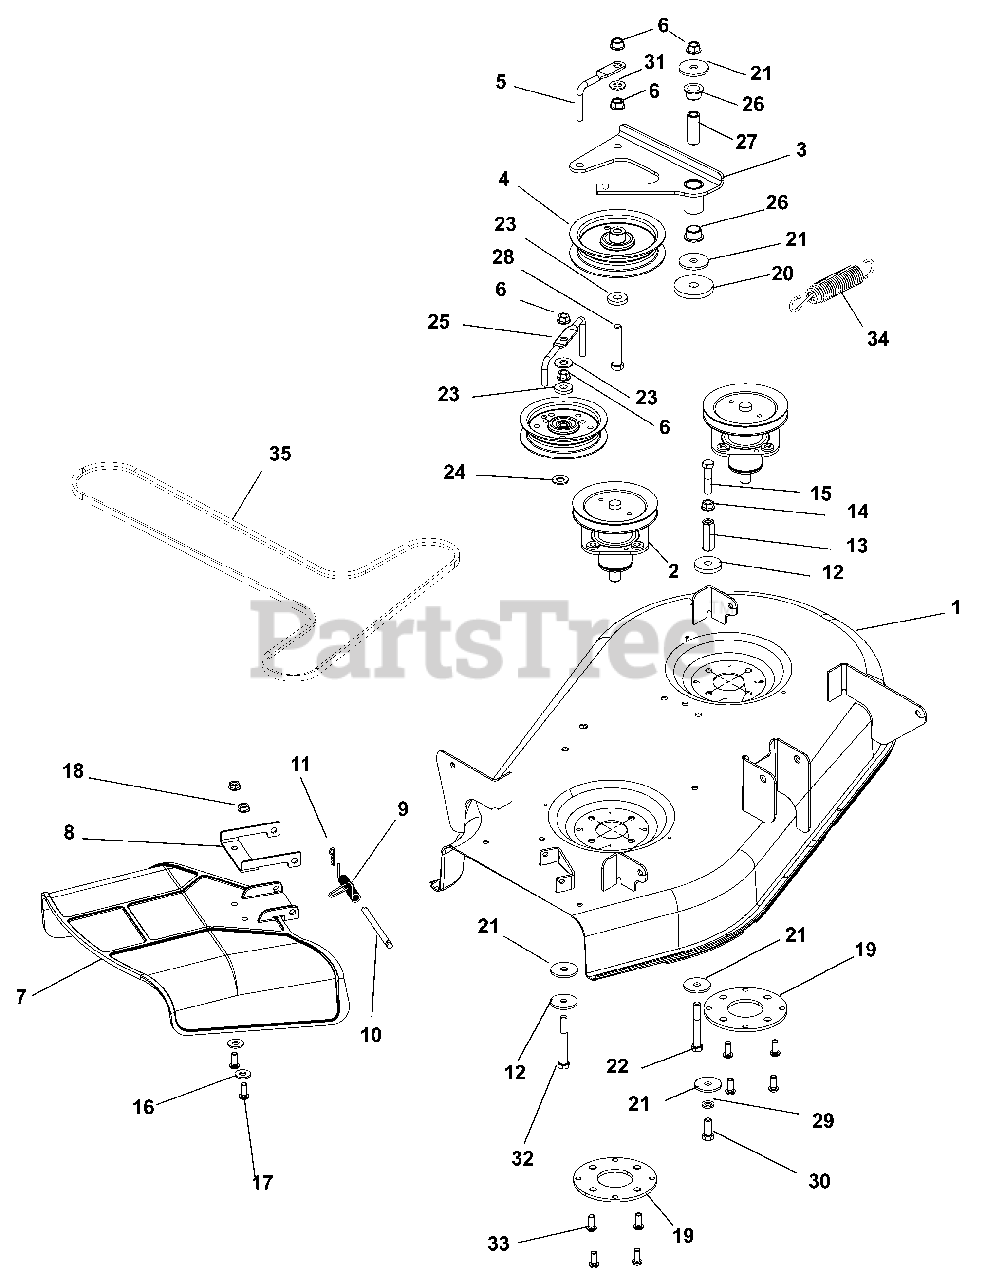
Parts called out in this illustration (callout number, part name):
1	Weldment, 34" Deck
2	Assembly, Spindle
3	Weldment, Idler Arm
4	Assembly, Idler 4"
5	Wireform, Belt Finger
6	Nut, Locking Top Flange .38-16
7	Chute, Side Discharge
8	Chute Reinforcement
9	Spring, Torsion
10	Pin, 5/16 x 3.88"
11	Pin, Hair Internal .08 x .18 x 1.18
12	Washer, Flat Steel .406 x 1.50 x .245
13	Nut, Coupling .375-16 x 1.75
14	Nut, Spin Lock, Flange .375-16
15	Bolt, Hex .38-16 x 1.75
16	Washer, Flat Steel .38 x .875 x .083
17	Screw, Socket Head .31-18 x .75 Button Head
18	Nut, Locking Top Flange .31-18
19	Plate, REINF, Spindle
20	Washer, Flat Steel .469 x 2.00 x .25
21	Washer, Flat Steel .380 x 1.50 x .125
22	Bolt, Hex .38-16 x 3.00
23	Washer, Flat Steel .406 x 1.00 x .188
24	Washer, Flat Steel .438 x 1.00 x .083
25	Belt Finger
26	Bushing, Flange, .625 x .750 x .500 x 1.00
27	Spacer, .375ID x .625D x 1.66 Promaster
28	Bolt, Hex .38-16 x 2.25
29	Washer, Locking .38 x .094 Regular
30	Bolt, Hex .38-16 x 1.00
31	Washer, Flat Steel .406 x .812 x .065
32	Bolt, Hex .38-16 x 2.75
33	Screw, Tapping .38-16 x .75 Hex Washer Head Thread Rolling
34	Spring, Tension .135 x .98 x 6.0
35	V-Belt, HA-Wrapped Clutching
